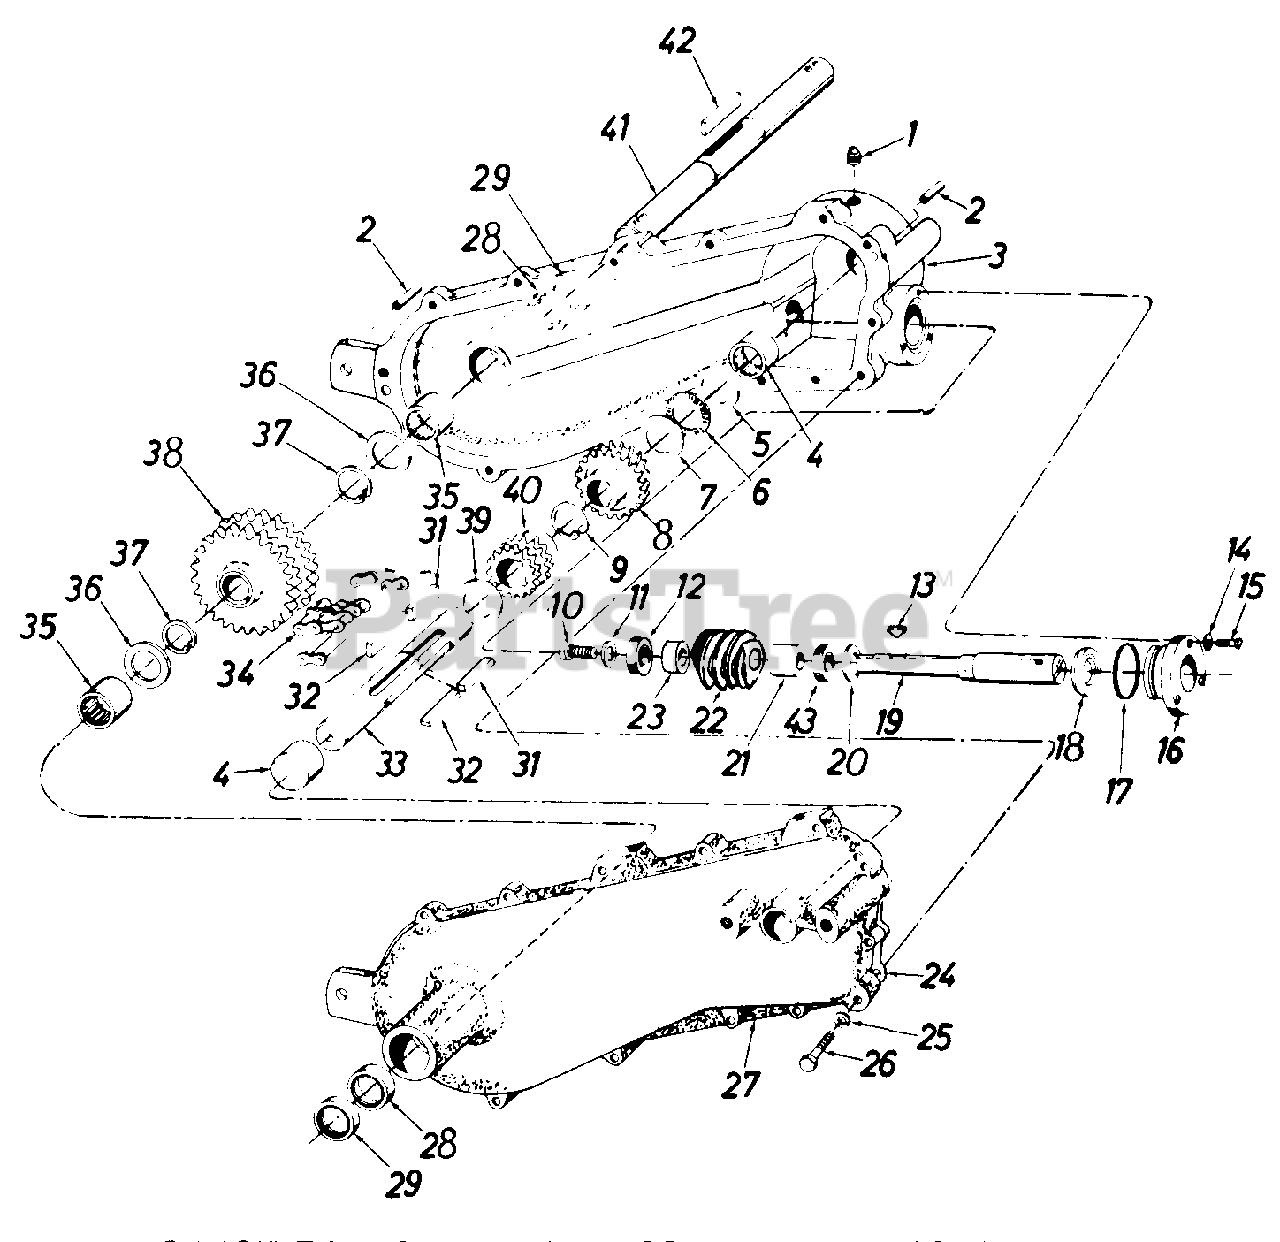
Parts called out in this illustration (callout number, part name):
1	Sq. Hd. Pipe Plug with Vent
2	Spring Pin Spiral 5/16" Dia. x 1.75" Lg.
3	Gear Case-L.H. Half
4	Needle Bearing
5	Thrust Race 1.25" I.D. x .126 Thk.
6	Thrust Bearing 1.25" I.D. x 1.977 O.D.
7	Thrust Race 1.25" I.D. x .303 Thk.
8	Worm Wheel
9	Snap Ring-for 1.25" Dia. Shaft
10	Hex Lock Scr. 5/16-24 x .75" Lg.
11	Belleville Wash. 5/16" Dia.
12	Ball Bearing .669 I.D. x 1.85 O.D. x .55
13	#9 Hi-Pro-Key 3/16" x 3/4" Dia.
14	L.-Wash. 1/4" Scr.*
15	Hex Scr. 1/4-20 x .88" Lg.*
16	End Cap
17	"O"-Ring
18	Oil Seal .875" I.D. x 1.503 O..D.
19	Worm InputShaft
20	Fl.-Wash. .793 I.D. x 1.240 0.D.
21	Clutch Idler Bushing
22	Worm Gear
23	Spacer
24	Gasket
25	L.-Wash. 5/16" Scr.*
26	Hex Scr. 5/16-18 x 1.75" Lg.*
27	Gear Case-R.H. Half
28	Oil Seal 1.25" I.D. x 2.004" O.D.
29	Oil Seal 1.25" I.D. x 2.004" O.D.
31	Sq. Key 5/16 x 1.25" Lg.*
32	Sq. Key 5/16 x 1.75" Lg.*
33	Worm Gear Shaft
34	Chain w/master link #60 x 39
35	Needle Brg. 1.25" I.D. x 1.927" O.D.
36	Thrust Bearing
37	Tru arc Snap Ring
38	Sprocket-25 Teeth
39	Thrust Bearing
40	Sprocket 13 Tooth
41	Tine Shaft
42	Sq. Key 5/16" x 2.0" Lg.*
43	Ball Bearing.787 I.D. x 2.048 O.D.
